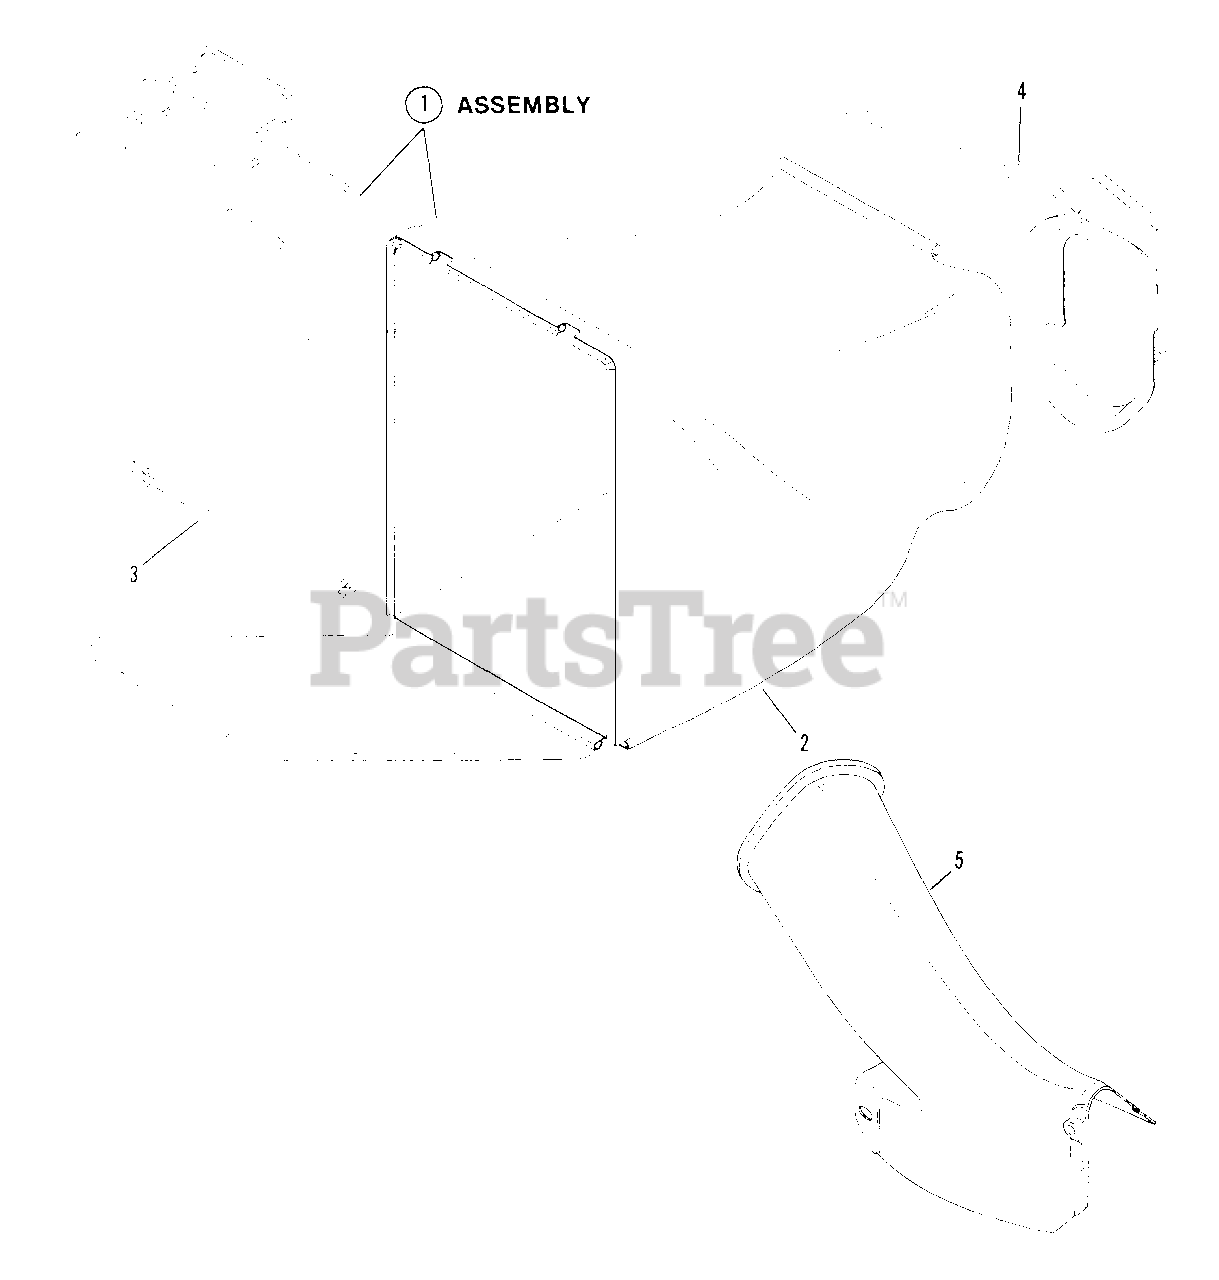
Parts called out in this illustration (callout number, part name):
1	ASSEMBLY, Grass Bag
2	BAG, Door Type (Charcoal)
3	ASSEMBLY, Bag Wire
4	CONNECTOR, Grass Bag
5	ADAPTER, Bag
